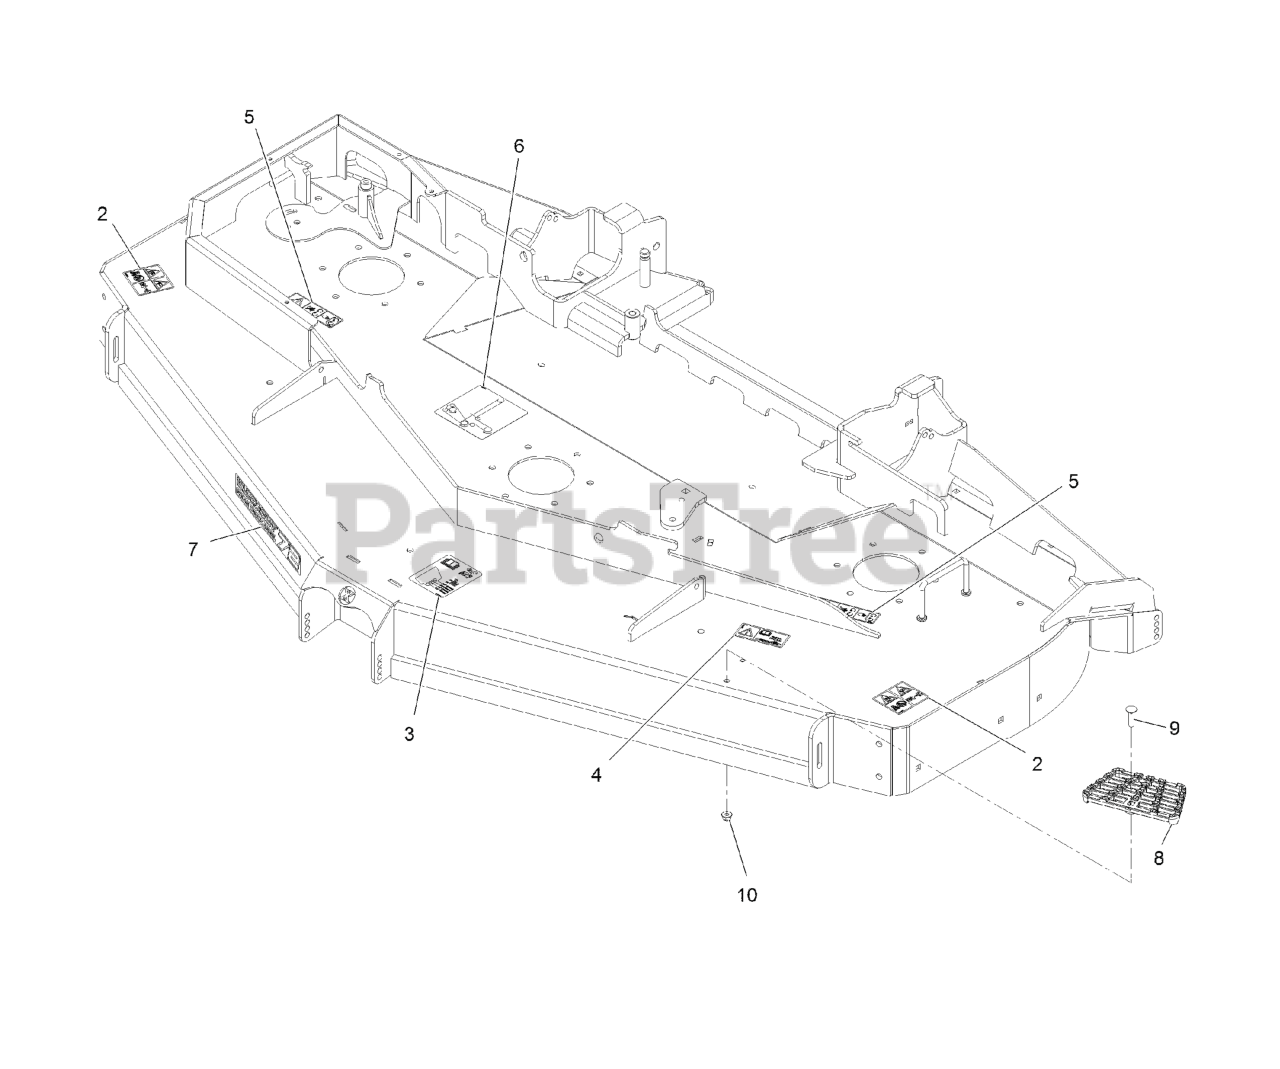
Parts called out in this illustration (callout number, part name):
2	DECAL-DANGER, THROWN OBJECT
3	DECAL-ROLLER, ANTI-SCALP
4	DECAL-TORQUE, BOLT
5	DECAL-COVER, MISSING
6	DECAL-ROUTING, BELT
7	Decal, 72Rd
8	STEP-DECK
9	Bolt-Carriage 5/16-18 X 1 1/4
10	NUT-HF, NI
